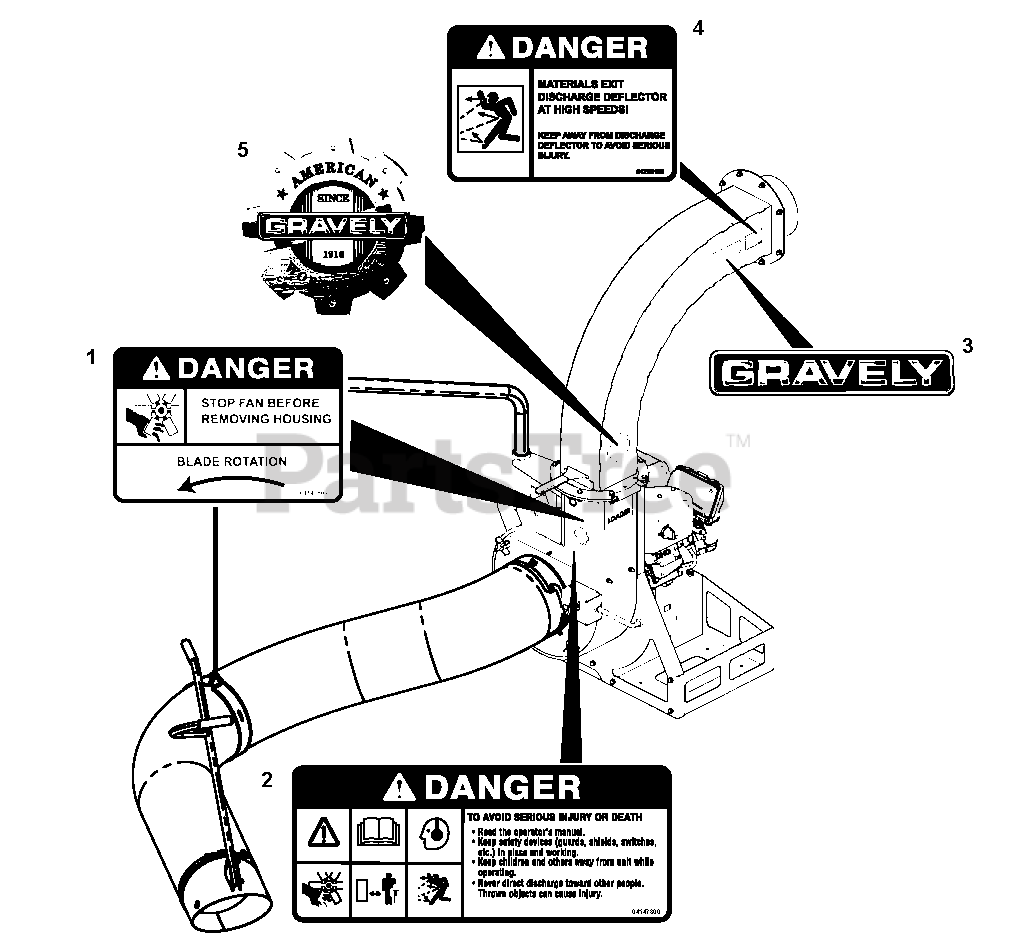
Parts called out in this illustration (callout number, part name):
1	Decal, Danger Blade Rotation
2	Decal, Danger Read Manual
3	Decal, 9.5" Gravely Logo
4	Decal, Danger Materials Exit
7	Decal, Gravely Heritage
